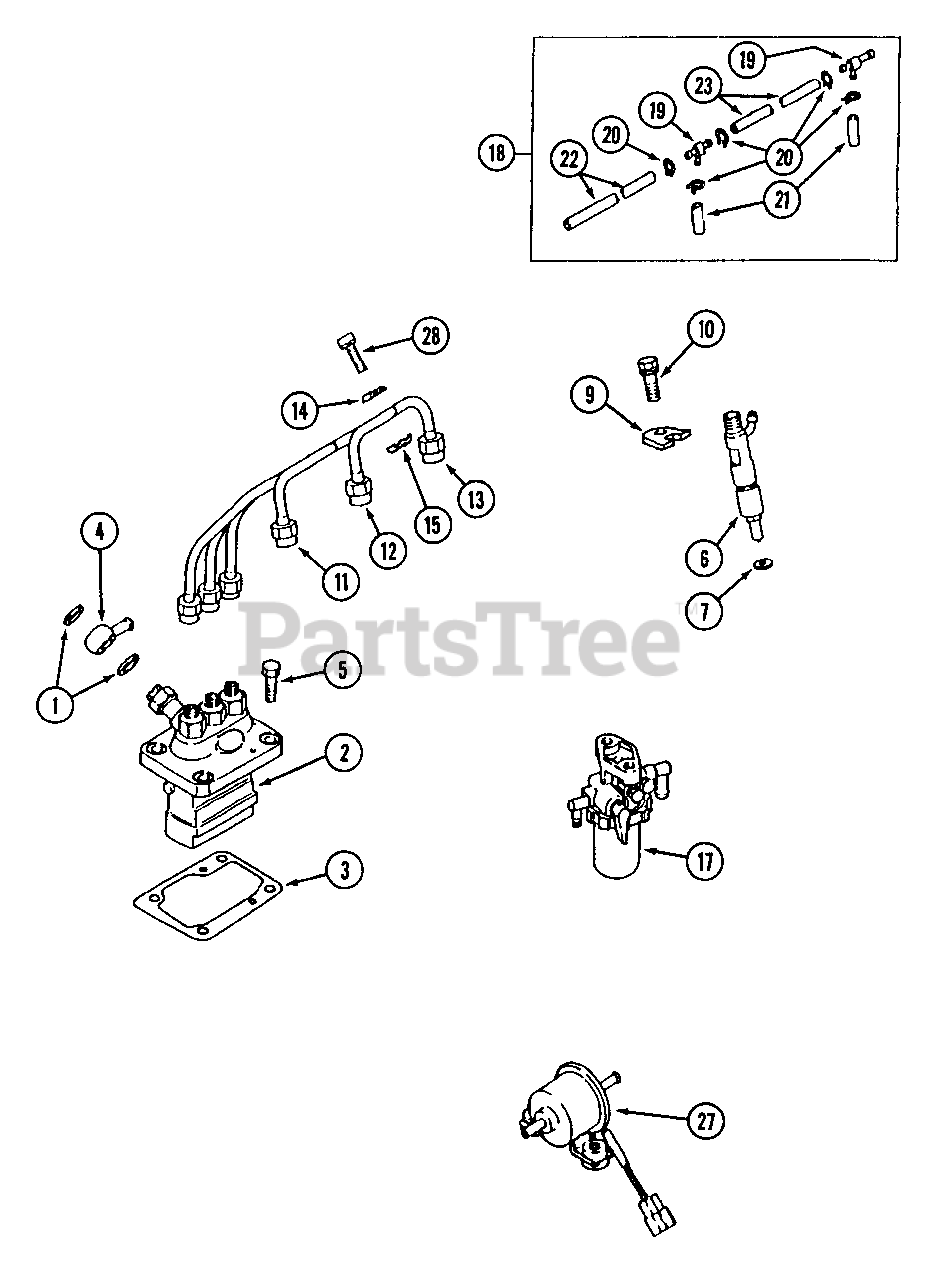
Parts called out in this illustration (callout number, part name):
4	Collar, Union
5	Bolt
6	Nozzle Ass'y.
7	Gasket, Nozzle
9	Support, Nozzle
10	Bolt,
11	Pipe Ass'y. No. 1
12	Pipe Ass'y. No. 2
13	Pipe Ass'y. No. 3
17	Filter Ass'y.
20	Clamp, Hose
21	Pipe, Rubber
22	Pipe, Rubber
23	Pipe, Rubber
27	Fuel Pump Ass'y.
28	Bolt,
